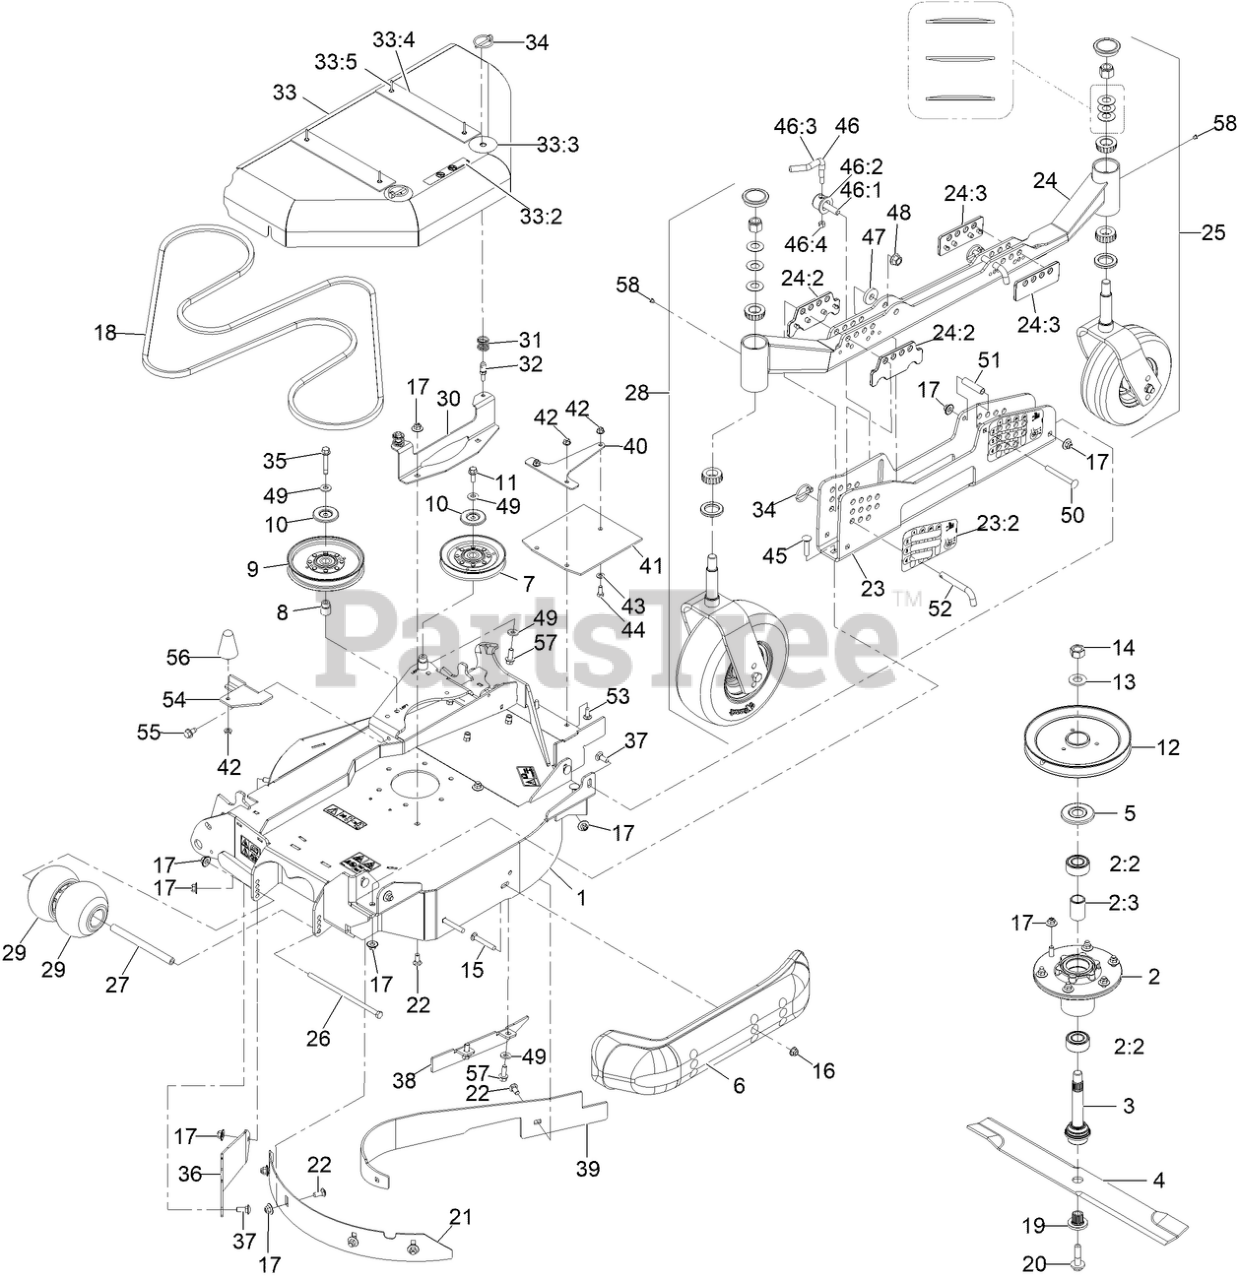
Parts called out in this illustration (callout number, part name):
1	ASM-Deck, LH Wing 96
2	ASM-CUTTER HSG
2:2	BEARING-3205 TRASHGUARD
2:3	SPACER-BEARING
3	ASM-SPINDLE AND SEAL
5	GUARD-BEARING, TOP
6	SKID-BUMPER, DECK
7	IDLER-V
8	BUSHING-IDLER
9	IDLER-PULLEY
10	SHIELD-DUST
11	SCREW-HHF 3/8-16 X 1
12	SHEAVE-SINGLE 96RD
14	NUT-HEX
15	SCREW-CARR
16	NUT-HF, NI
17	Nut-Nyloc 3/8-16 Flg
19	BUSHING,SPLINED
20	SCREW,SEMS 1/2-20 X 2.19
21	BAFFLE-DEPTH, LH
22	BOLT-CARR
23	ASM-CHANNEL, HOC LH
23:2	DECAL-HEIGHT OF CUT-LH
24	ASM-LH GAUGE WHEEL ARM
24:2	PLATE-GUIDE, FRONT
24:3	PLATE-GUIDE, REAR
25	Caster/Wheel ASM
26	SCREW-HH
27	SPACER-WHEEL
29	ROLLER-SCALP, ANTI
30	BRACKET-SHIELD MOUNT, OUT
32	PIN, SPRING
33	ASM-Wing Shield LH
33:2	DECAL-NO STEP
33:3	DECAL-SCRATCH COVER
33:4	Plate-Uhmw 2"
33:5	Rivet-Pop
34	PIN-LYNCH
35	SCREW-HHF
36	PLATE-FILL, LH DECK
37	BOLT-CARR
38	Fin-Baffle, Discharge Wing (LH)
39	BAFFLE-DOGLEG, CENTER (RH
40	SUPPORT-FLAP, LH
41	GUARD-TIRE, LH
42	NUT-HF, NI
43	WASHER-PLAIN
44	SCREW-HH
45	SCREW-CARR
46	LEVER ASM
46:1	SCREW-LOCK
46:2	CAP-LOCK
46:4	NUT-LOCK, NI
48	Nut-Lock 1/2-13
49	WASHER-BELLEVILLE
50	SCREW-CARR
52	PIN-HOC
53	BOLT-CARR
54	BRACKET-COVER RETAINER
55	SCREW-HWH
56	BUMPER-RUBBER
57	SCREW-HHF
